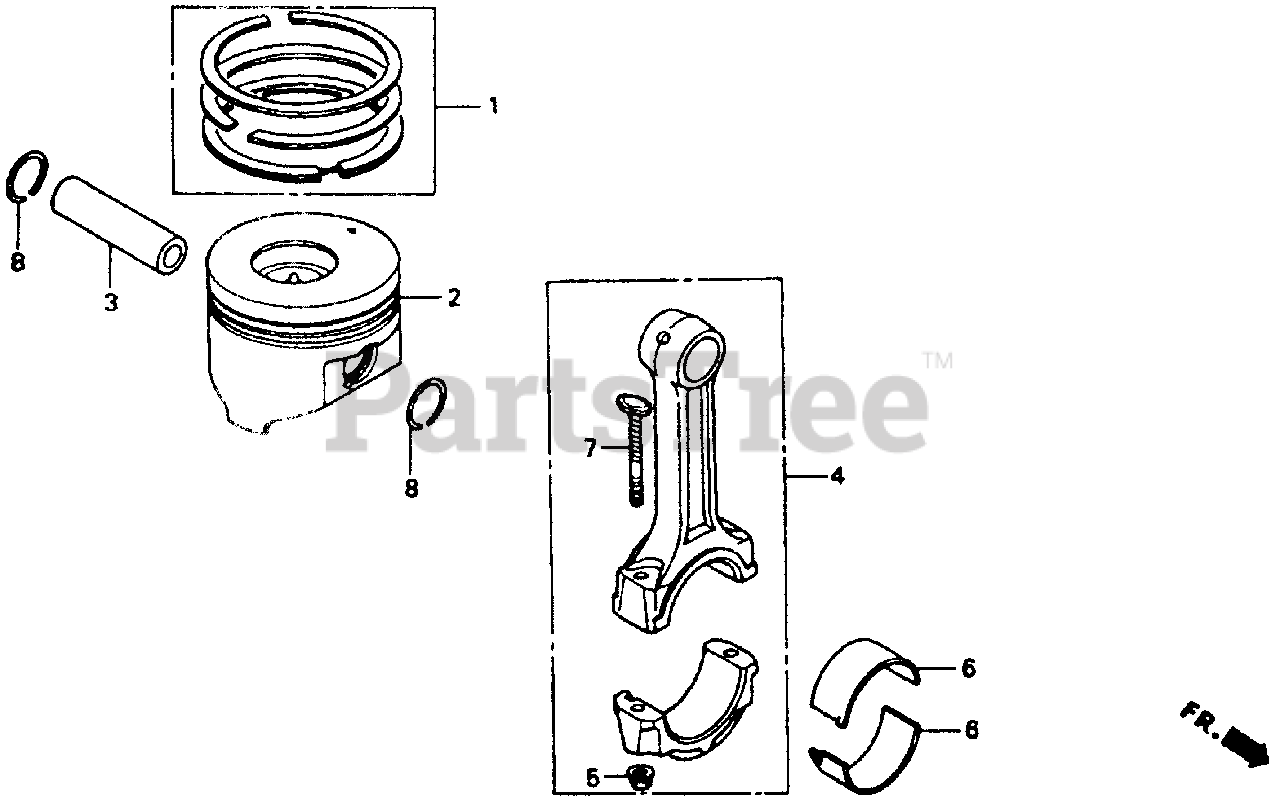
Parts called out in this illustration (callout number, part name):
1	RING SET, PISTON (STD)
1	RING SET, PISTON (OS 0.25)
1	RING SET, PISTON (OS 0.50)
1	RING SET, PISTON (0.75)
2	PISTON (STD)
3	PIN, PISTON
4	ROD ASSY., CONNECTING
5	NUT, CONNECTING ROD
6	BEARING A, CONNECTING ROD (BLUE)
6	BEARING B, CONNECTING ROD (BLACK)
6	BEARING C, CONNECTING ROD (BROWN)
6	BEARING D, CONNECTING ROD (GREEN)
6	BEARING E, CONNECTING ROD (YELLOW)
6	BEARING F, CONNECTING ROD (PINK)
6	BEARING G, CONNECTING ROD (RED)
6	BEARING A, CONNECTING ROD (US 0.25) (BLACK)
6	BEARING B, CONNECTING ROD (US 0.25) (BROWN)
6	BEARING C, CONNECTING ROD (US 0.25) (GREEN)
6	BEARING A, CONNECTING ROD (US 0.75) (BLACK)
6	BEARING B, CONNECTING ROD (US 0.75) (BROWN)
6	BEARING C, CONNECTING ROD (US 0.75) (GREEN)
7	BOLT, CONNECTING ROD (NAGOYA NEJI)
8	CLIP, PISTON PIN (1.2X20)
